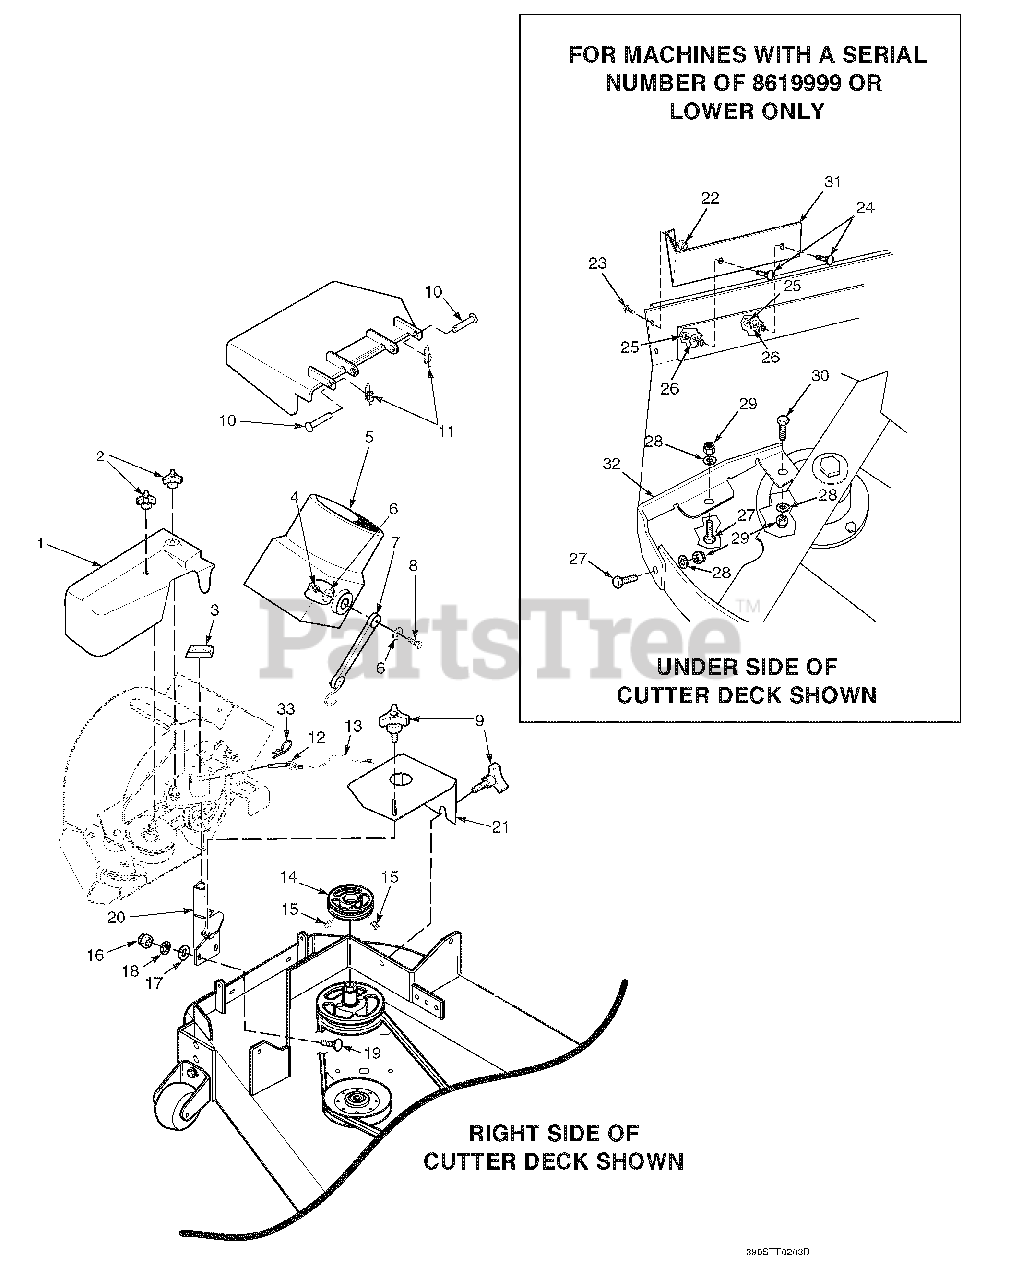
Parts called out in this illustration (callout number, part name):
1	Belt Cover, GC-STT - 61" & 72"
2	Wingnut, Plastic 3/8" Small
3	Cap, Square Vinyl
4	Nut, Elastic Stop 1/4-20
5	Adapter w/Strap
6	Flatwasher, 1/4-.312 x .750 x .065
7	Rubber Strap 7-3/4"
8	Bolt, Hex Head 1/4-20 x 1-1/4"
9	Knob W/Stud, 3/8-16 x 1-1/4"
10	Clevis Pin, 5/16 x 1-1/2"
11	Pin, Rue Cotter 5/16 Dia.
12	Pin, Ring 1/2 x 2-1/4"
13	Lanyard
14	Pulley, 5-1/2" for 61" Deck
15	Setscrew, 5/16-18 x 3/8"
16	Nut, Elastic Stop 1/2-13
17	Flatwasher, 1/2-.531 x 1.062 x .095
18	Lockwasher, 1/2"
19	Bolt, Hex Head 1/2-13 x 1-1/2" Grade 5
20	Mounting Post Weldment, Blower - 61"
21	Belt Cover, - 61"
22	Nut, Serrated Flange 1/4-20
23	Bolt, Hex Head 1/4-20 x 3/4"
24	Bolt, Carriage 3/8-16 x 1"
25	Nut, Elastic Stop 3/8-16
26	Flatwasher, 3/8-.391 x .938 x .105
27	Bolt, Hex Head 5/16-18 x 1"
28	Flatwasher, 5/16-.375 x .875 x .083
29	Nut, Elastic Stop 5/16-18
30	Bolt, Hex Head 5/16-18 x 1-3/4"
31	Baffle, 61"
32	Baffle, 61" Deck
33	Hair Pin Cotter, .177 x 3-1/4"
